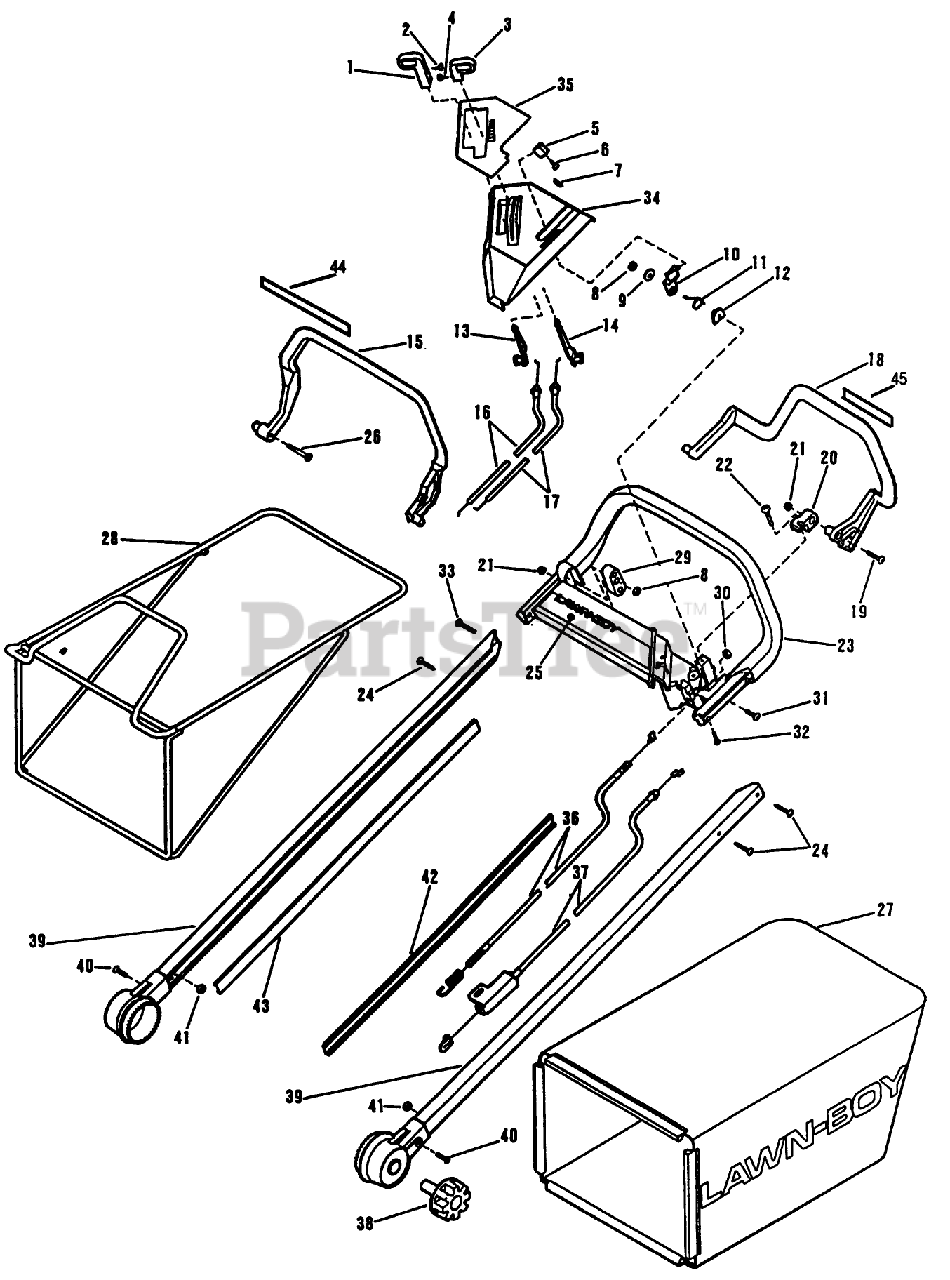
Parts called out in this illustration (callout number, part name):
1	KNOB & SCREW AY
8	LOCKNUT E
10	BBC LATCH LB
11	SPRING
16	CABLE AY. WESCON
17	CABLE
18	BAIL-S.P. *
20	PIVOT BAIL PL
21	LOCKNUT FLAN
24	SCREW
29	BLOCK BAIL PL
31	SCREW-CROSS RECESS
33	SCREW-TRUSS
37	CABLE AY WESC
38	KNOB-HDLE MT.ASM*B
41	LOCKNUT FLAN
44	Decal-BBC
